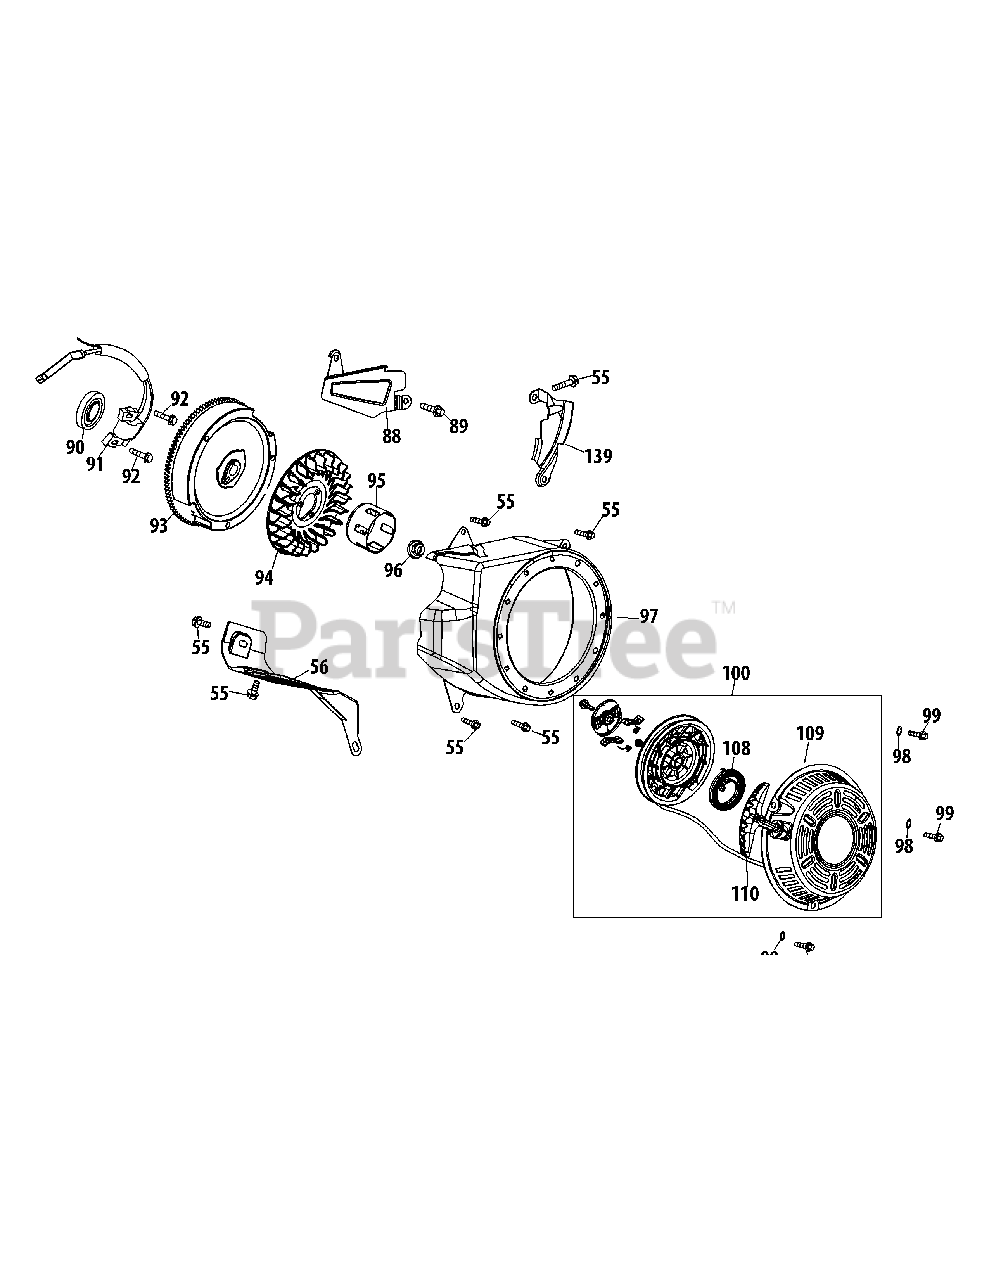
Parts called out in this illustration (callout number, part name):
55	Bolt M6×12
56	Air Shield
88	Air Flow Shield
89	Bolt M6×10
90	Oil Seal 25×41.25×6
91	Ignition Coil Assembly
92	Bolt M6×25
93	Flywheel
94	Cooling Fan
95	Starter Cup
96	Flywheel Nut, M14 X 1.5
97	Blower Housing
98	Washer 6
99	Bolt M6×10
100	Recoil Starter
108	Recoil Spring
109	Recoil Assembly
110	Starter Handle
139	Lower Shield
